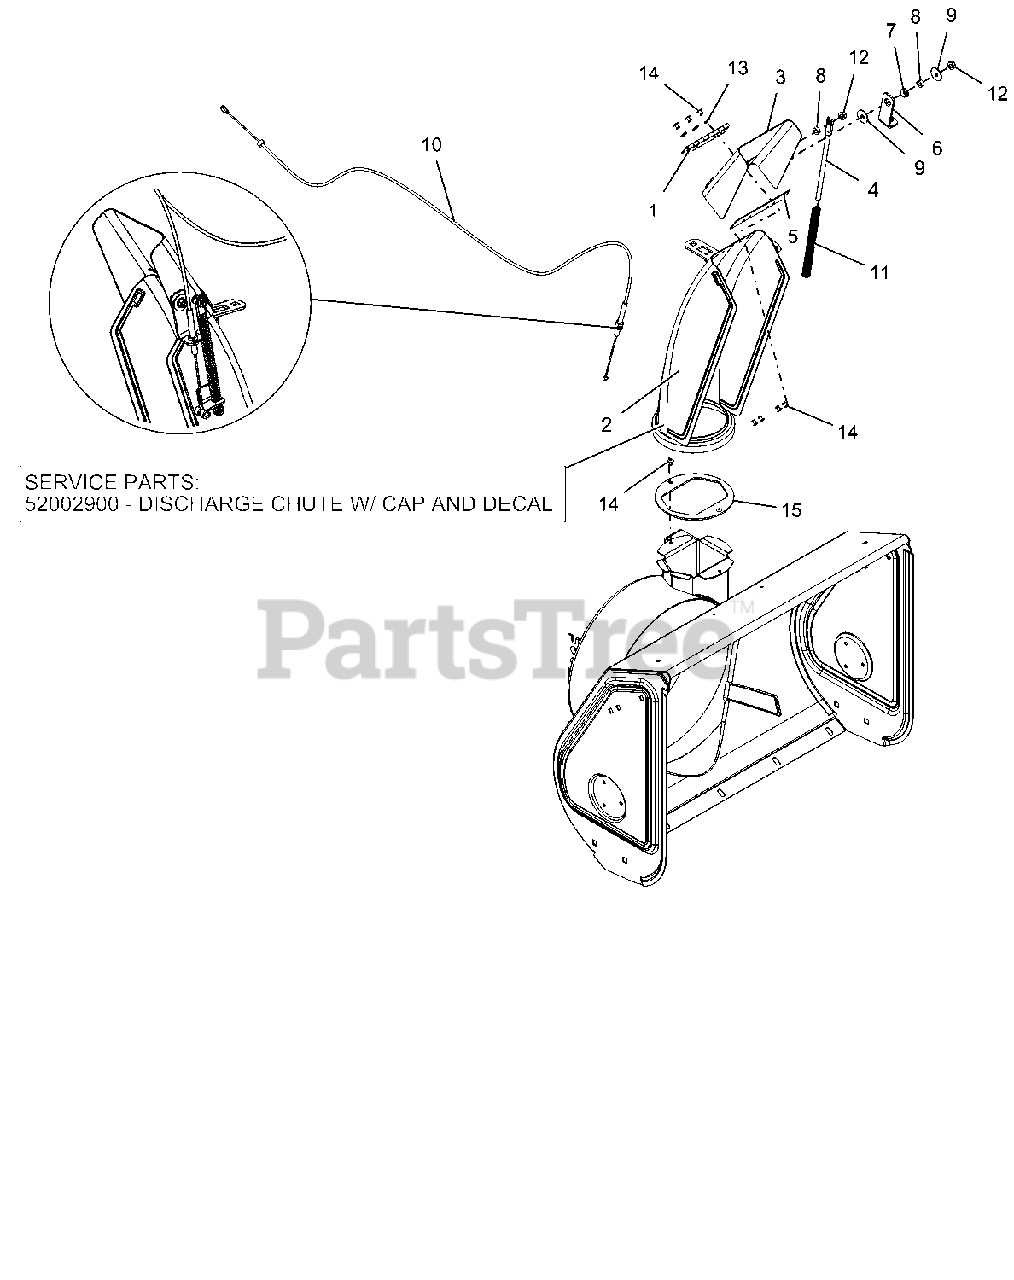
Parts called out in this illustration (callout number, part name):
2	CHUTE, COMPACT-TALL W/REMOTE
3	CAP, COMPACT-W/REMOTE
4	ROD, DEFLECTOR CAP
5	CAP SEAL 5.25
6	BRACKET, CABLE ANCHOR
7	BUSHING, POLYLINER-.50 SNAPIN
8	BSHG-SLV .265X.500X.219
9	WSHR-FL-STL .281X1.000X.063
10	CABLE, DEFLECTOR - COMPACT
11	SG-COMP .08X.40X6.50 14#/IN
12	@NUT-LK-TOP-FLG .25-20 YWZC
13	WSHR-FL-STL .196X.500X.06 YZ
14	RVT-POP .187 YZ
15	BAFFLE, COMPACT DISCHARGE
16	CHUTE, DISCHARGE W/REM.CAP,DEC
